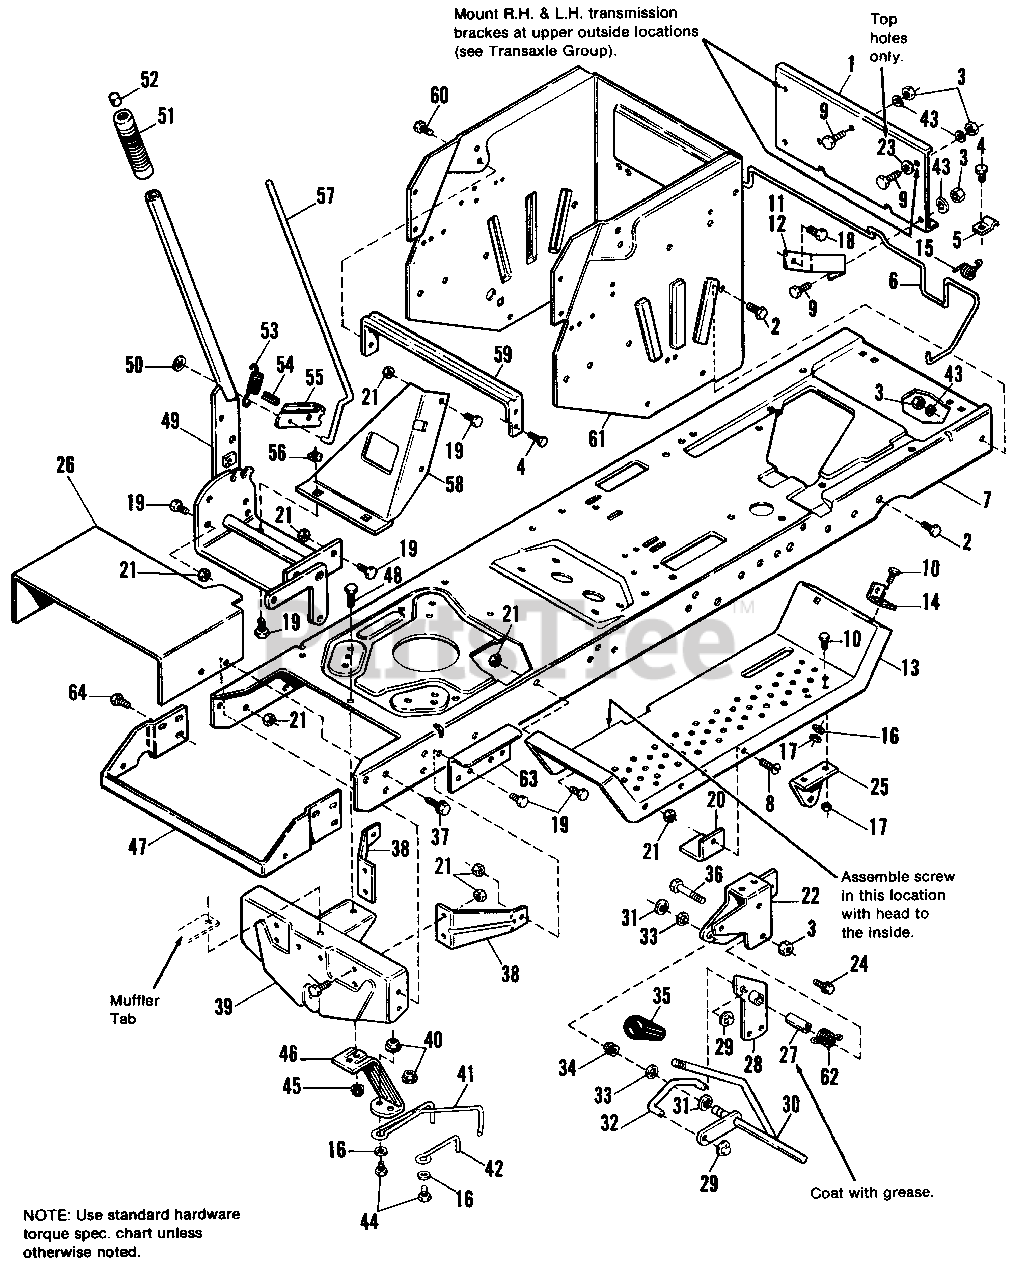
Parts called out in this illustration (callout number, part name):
2	CAPSCREW, 3/8-16 x 1
3	NUT, Hex, 3/8-16
4	SCREW, Taptite, 5/16-18 x 1/2
6	ROD, Seat Latch
8	SCREW, Slotted. 5/16-18 x 3/4
9	CAPSCREW, 3/8-16 x 1-1/4
10	CAPSCREW, 1/4-20 x 5/8
11	BRACE, Drawbar, L.H.
12	BRACE, Drawbar, R.H.
14	BRACKET, Seat Latch
15	SPRING, Torsion
16	WASHER, Plain, 1/4 Std.
17	NUT, Hex, 1/4-20
18	SCREW, Taptite, 3/8-16 x 3/4
19	CAPSCREW, 5/16-18 x 3/4
20	UP-STOP, Mower
21	NUT, Hex, 5/16-18 (Qty. 25 on 1691766)
22	BRACKET, PTO Lever Mtg.
24	SCREW, Taptite, 1/4-20 x 1/2
25	SUPPORT, PTO Lever
26	SHIELD, Heat, Lower (1691766 only)
28	ARM ASSY, PTO Link
29	NUT, Pal, 3/8
30	LEVER ASSY., PTO
31	RING, Snap
32	Link, PTO
34	BUSHING, Split (Nylon)
35	KNOB
36	CAPSCREW, 3/8-16 x 2-1/4
37	SCREW, Taptite, 5/16-18 x 3/4
38	BRACE, Axle Support
39	SUPPORT ASSY., Axle
40	NUT, Hex, Flange Lock, 5/16-18
43	LOCKWASHER, 3/8
44	CAPSCREW, 5/16-18 x 7/8
45	NUT, Whiz Flange, 5/16-18
46	SUPPORT, Belt Guide
47	SUPPORT, Hood
48	CAPSCREW, Whiz Flange, 5/16-18 x 1-1/4
49	LEVER ASSY., Lift
50	NUT, Push On
51	GRIP
54	PIN, Spring, 3/8 x 1
55	LATCH, Lift Lever
56	NUT, Speed, 5/16-18
58	BRACE, Lift Lever
59	BRACE, Seat (Wrapper)
60	SCREW, Taptite, 5/16-18 x 1
61	SUPPORT, Axle (Wrapper)
62	SPRING, Torsion
63	DEFLECTOR, Air (1691766 only)
64	SCREW, Whiziock, 5/16-18 x 3/4
